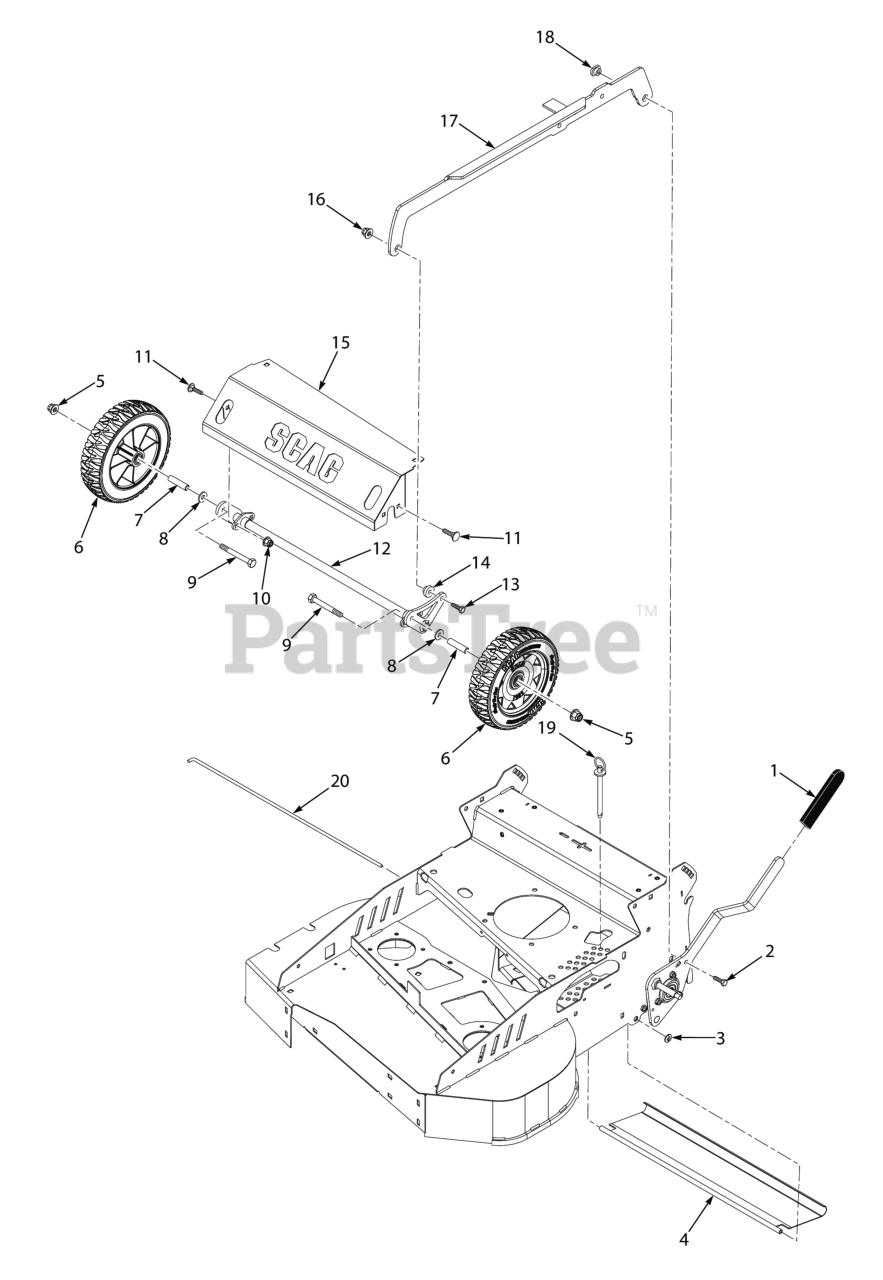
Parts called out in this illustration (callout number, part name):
1	Grip, Deck Lift
2	Bolt, Hex Head, 3/8-16 x 3/4"
3	Nut, Push-On 5/16-18
4	Trail Shield
5	Nut, Flange Elastic Stop Nut, 3/8-16
6	Wheel Assembly, Front
7	Spacer, Front Wheel
8	Flatwasher, 3/8 (.391 x .938 x .105 HD) Grade 8
9	Capscrew, Hex Head 3/8-16 x 2.75"
10	Nut, Flange Head Elastic Stop 5/16-18
11	Bolt, 5/16-18 x .75 RHSN Carriage
12	Weldment, Front Axle
13	Bolt, Hex Head 3/8-16 x 1-1/4", Kawasaki FX / FT & FT-EFI
14	BUSHING, SPEED ADJUSTMENT LEVER
15	Weldment, Front Axle Support
16	Nut, Flange Elastic Stop Nut, 3/8-16
17	Weldment Deck Lift
18	Pivot, Deck Weldment
19	Ring Pin, 3/8 x 4"
20	Rod, Trail Shield
